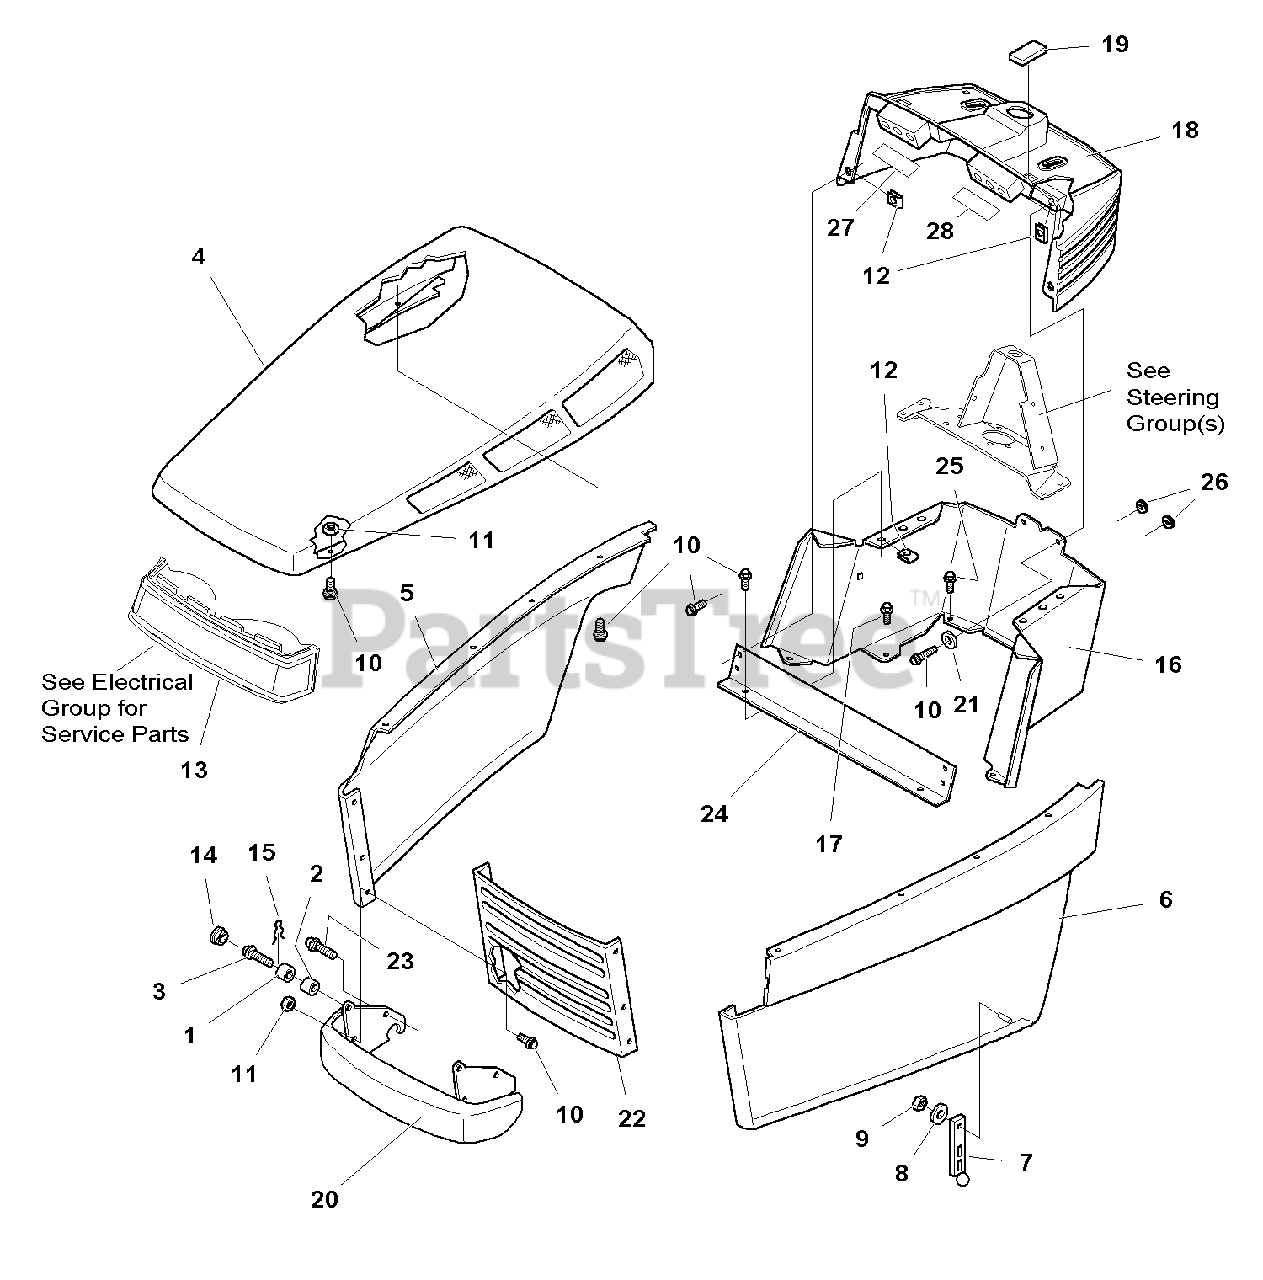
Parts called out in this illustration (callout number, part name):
2	PIVOT, Hood
3	CAPSCREW, Hex Head, Taptite, 5/16-18 X 1
4	HOOD, Orange
5	SIDE PANEL ASSEMBLY, RH, Orange
5	SIDE PANEL ASSEMBLY, RH, Red
6	SIDE PANEL ASSEMBLY, LH, Orange
6	SIDE PANEL ASSEMBLY, LH, Red
7	STRAP, Hood
8	WASHER, 3/16
9	NUT, Hex Nylon Lock, #10-24
10	CAPSCREW, Hex Head, Whiz Lock, 1/4-20 x 5/8
11	NUT, Hex Nylon Lock, 1/4-20
12	PAL NUT, 1/4-20
13	HEADLIGHT ASSEMBLY (See Electrical Group for Service Parts)
14	SPACER, Hood
15	CLIP, Hairpin
16	DASH ASSEMBLY, Lower
17	CAPSCREW, Hex Head, Taptite, 1/4-20 x 1/2
18	DASHBOARD ASSEMBLY (Liquid Cooled Models)
20	BUMPER ASSEMBLY
21	WASHER, 1/4
23	CAPSCREW, Hex Head, Taptite, 5/16-18 x 5/8
24	SUPPORT, Upper Dash
25	CAPSCREW, Hex Head, Taptite, 1/4-20 x 3/8
27	DECAL, R. H. Indicator
28	DECAL, L. H. Indicator
